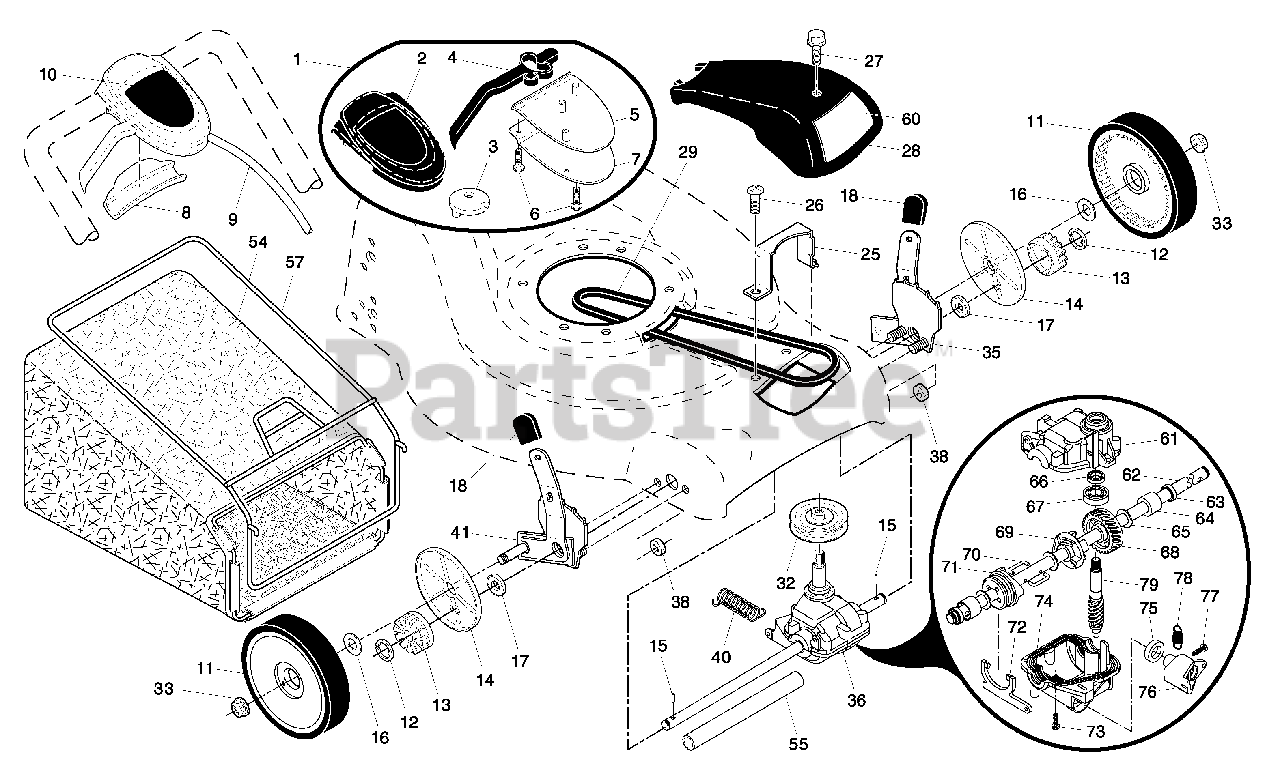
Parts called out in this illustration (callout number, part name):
1	Drive Control Assembly
2	Cover, Drive Control, Upper
4	Lever, Drive Control
5	Cover, Drive Control, Lower
7	Mounting Bracket, Drive Control
8	Cap, Drive Control
9	Cable, Drive
10	Decal, Drive Cover
11	Wheel & Tire Assembly
13	Pinion
14	Dust Cover
15	Pawl, Drive
16	Washer 1/2 x 1-1/2 x .134
17	Bearing, Wheel Adjuster
18	Selector Knob
25	Belt Keeper
26	Screw
27	Pan Head Tapping Screw #10-24 x 2-3/4
28	Drive Cover
32	Drive Pulley
33	Locknut, Hex
35	Kit, Wheel Adjuster, LH
36	Gearcase Assembly, Complete
38	Locknut, Hex 1/4-20
41	Kit, Wheel Adjuster, RH
54	Grassbag Assembly
55	Driveshaft Cover
57	Frame, Grassbag
61	Case, Upper
62	Shaft, Output
63	Seal, Output Shaft
66	Seal, Worm Shaft
67	Bearing, Ball
68	Gear, 27 Teeth
69	Fixed Dog Clutch
71	Movable Dog Clutch
73	Screw, Case
74	Case, Lower
75	Seal, Lever
77	Screw, Lever
79	Shaft, Worm
